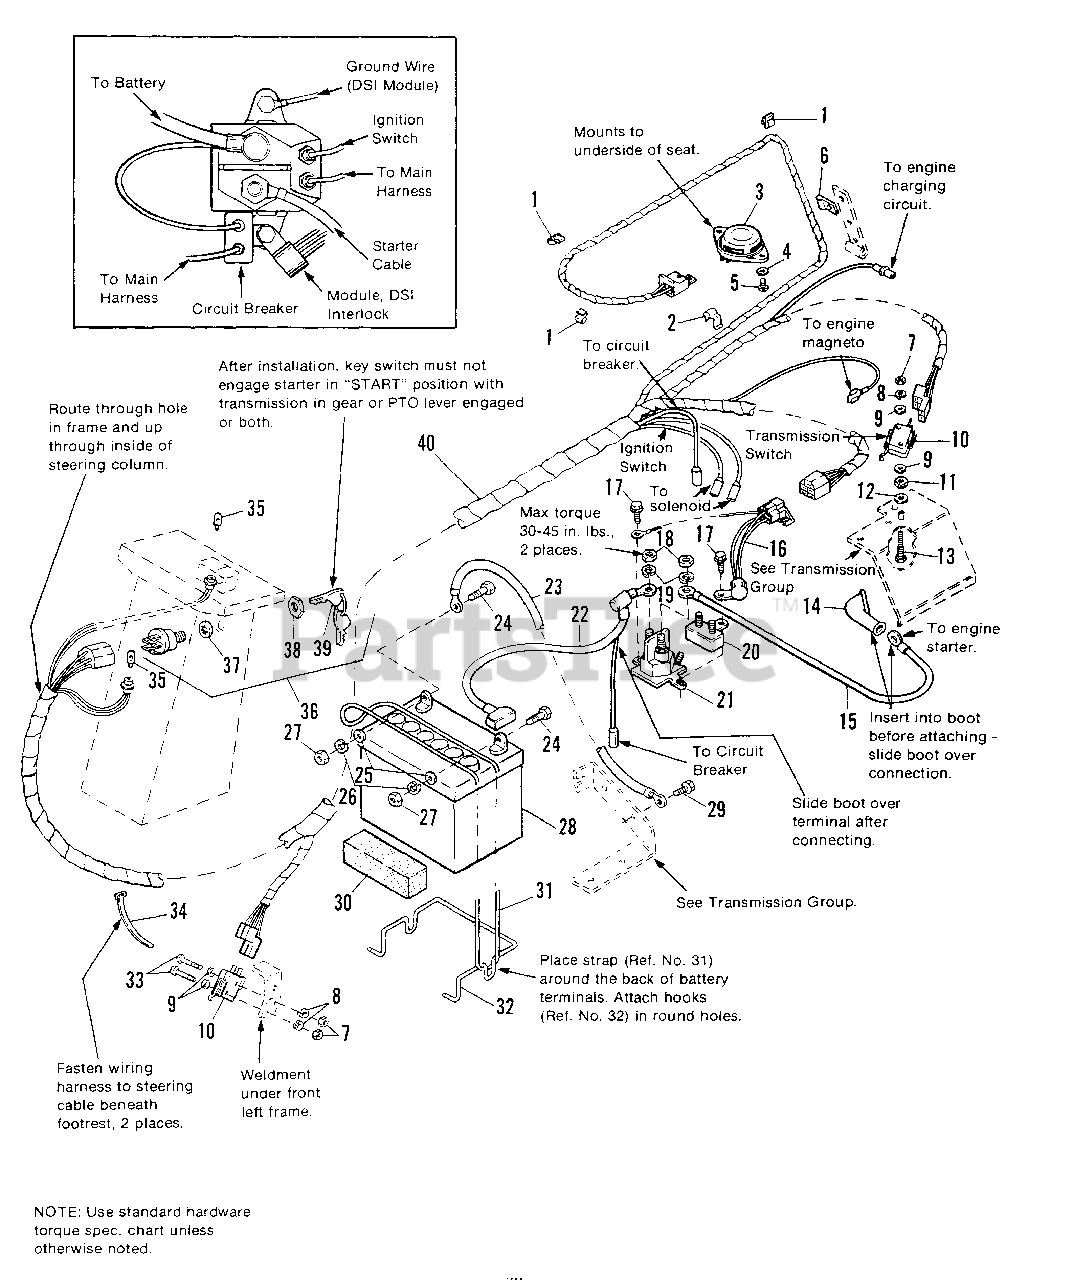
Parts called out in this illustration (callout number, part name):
1	CLIP, Wire
3	SWITCH, Seat (Used on all 1691330 and 1691198 after serial no. 1069.)
3	SWITCH, Seat (Used on 1691198 before serial no. 1070.)
4	LOCKWASHER, Ext., 1/4
5	SCREW, Rd. Hd., 1/4-20 x 1/2
6	CLAMP, Wire
7	NUT, Hex, #5-40
8	LOCKWASHER, #5
9	WASHER, #6
10	MICRO SWITCH, Tandem
11	LOCKNUT, Hex, 1/4-20
12	WASHER, 1/4
13	STUD, Switch, Mtg.
14	COVER, Terminal
15	CABLE ASSY., (Starter)
16	MODULE, DSI, Interlock (Used with Briggs & Stratton engine only.)
16	MODULE, DSI, Interlock (Used with Tecumseh engine only.)
17	SCREW, Taptite, 1/4-20 x 3/4, Pltd.
18	NUT, Hex, 5/16-24
19	LOCKWASHER, 5/16
20	CIRCUIT BREAKER
21	SOLENOID
22	CABLE ASSY. (Battery-Solenoid)
23	CABLE ASSY., (Battery Ground)
24	CAPSCREW, Hex, 1/4-20 x 3/4
25	WASHER, 1/4
26	LOCKWASHER, 1/4
27	NUT, Hex, 1/4-20
28	BATTERY, 12V
29	SCREW, Taptite, 5/16 x 1/2
30	PAD, Foam, Battery
31	STRAP, Battery
32	BRACE, Battery
33	SCREW, Rnd. Hd., #5-40 x 1-1/2
34	CABLE TY-WRAP
35	LAMP, Indicator
36	SWITCH, Ignition (Incl. Ref. Nos. 37, 38 & 39)
37	LOCKWASHER, Int. 5/8
38	NUT, 5/8-32
39	KEYS & RING
40	WIRING HARNESS
